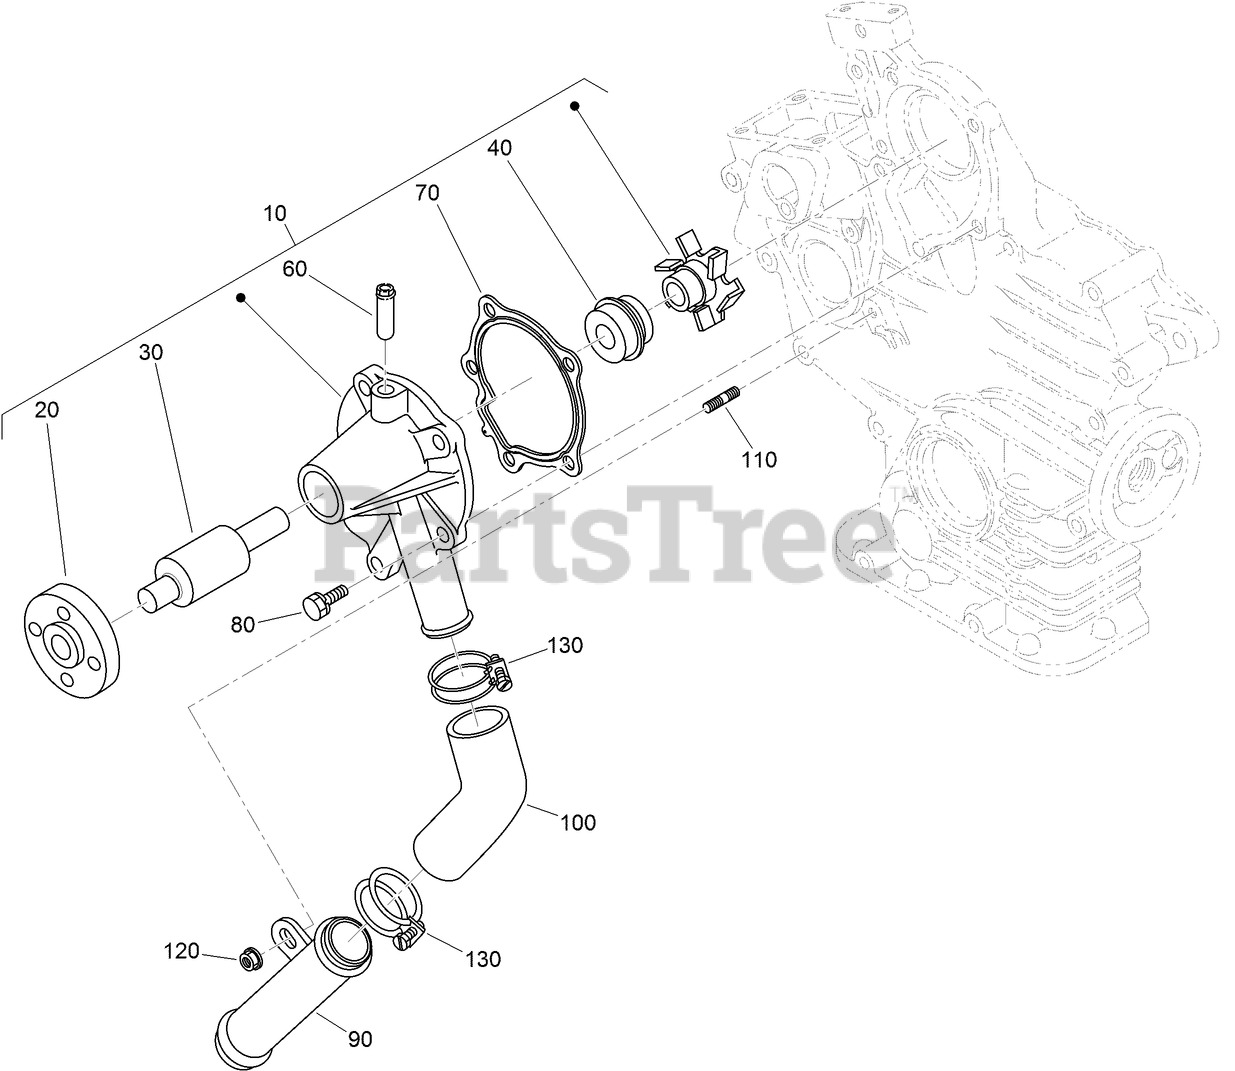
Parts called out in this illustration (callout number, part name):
10	WATER PUMP ASM
20	FLANGE-PUMP, WATER
30	BEARING-BALL
40	WATER PUMP SEAL ASM
60	PIPE-RETURN, WATER
70	GASKET-PUMP, WATER
90	PIPE-WATER
100	PIPE-WATER
120	NUT-FLANGE
130	BAND-PIPE
